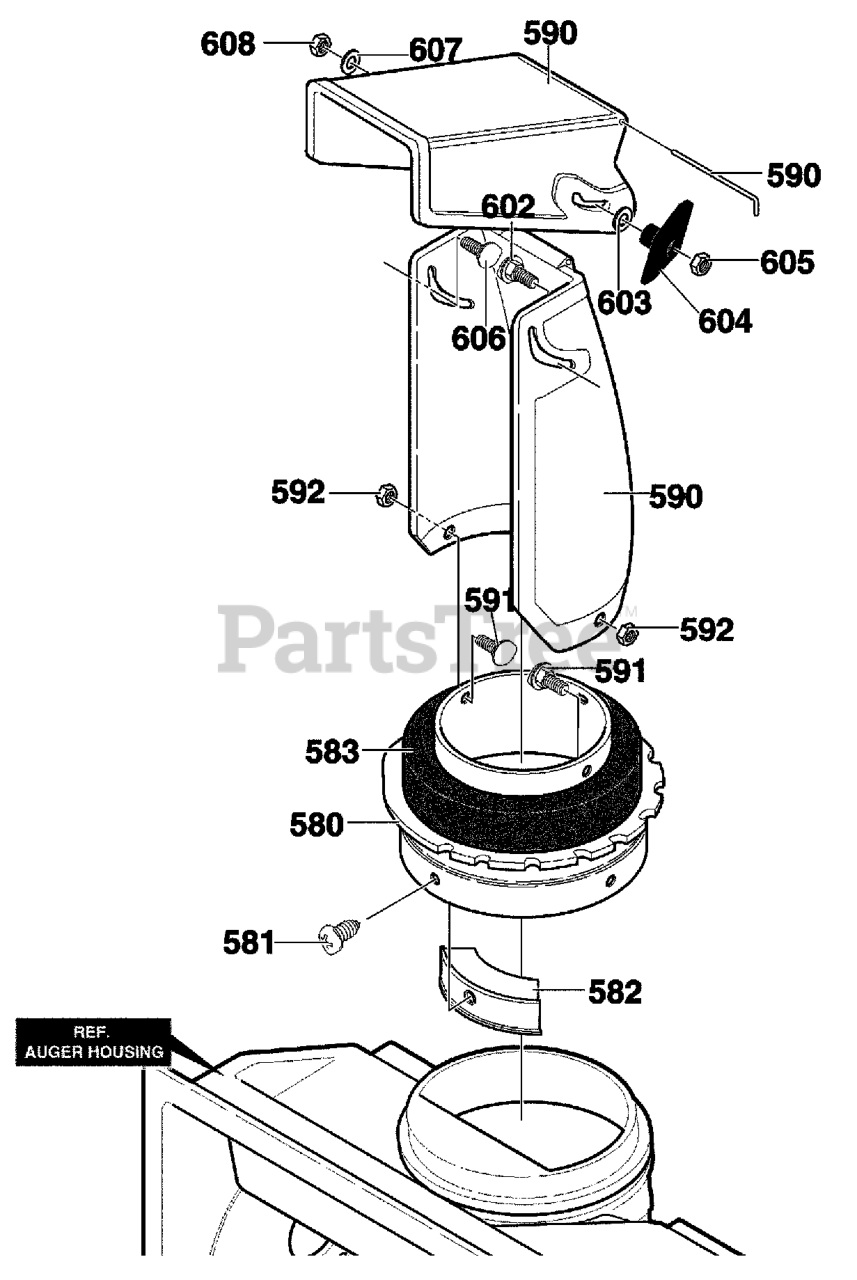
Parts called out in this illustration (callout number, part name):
580	RING, CHUTE
581	SCREW, #10X.50
582	GUIDE, CHUTE
583	DONUT FOAM
590	CHUTE ASSY.
591	SCREW 1/4-20X.50
592	NUT, CNTRLK 1/4-20
602	BOLT, 5/16-18X1.25 CARR.
603	WASHER, FLAT .349X.69X.066
604	KNOB, T
605	NUT, 5/16-18 REGHEX
606	SCREW, 5/16-18 x 0.75
607	WASHER, FLAT .349X.69X.066
608	NUT, 5/16-18 REGHEXCTRLK
